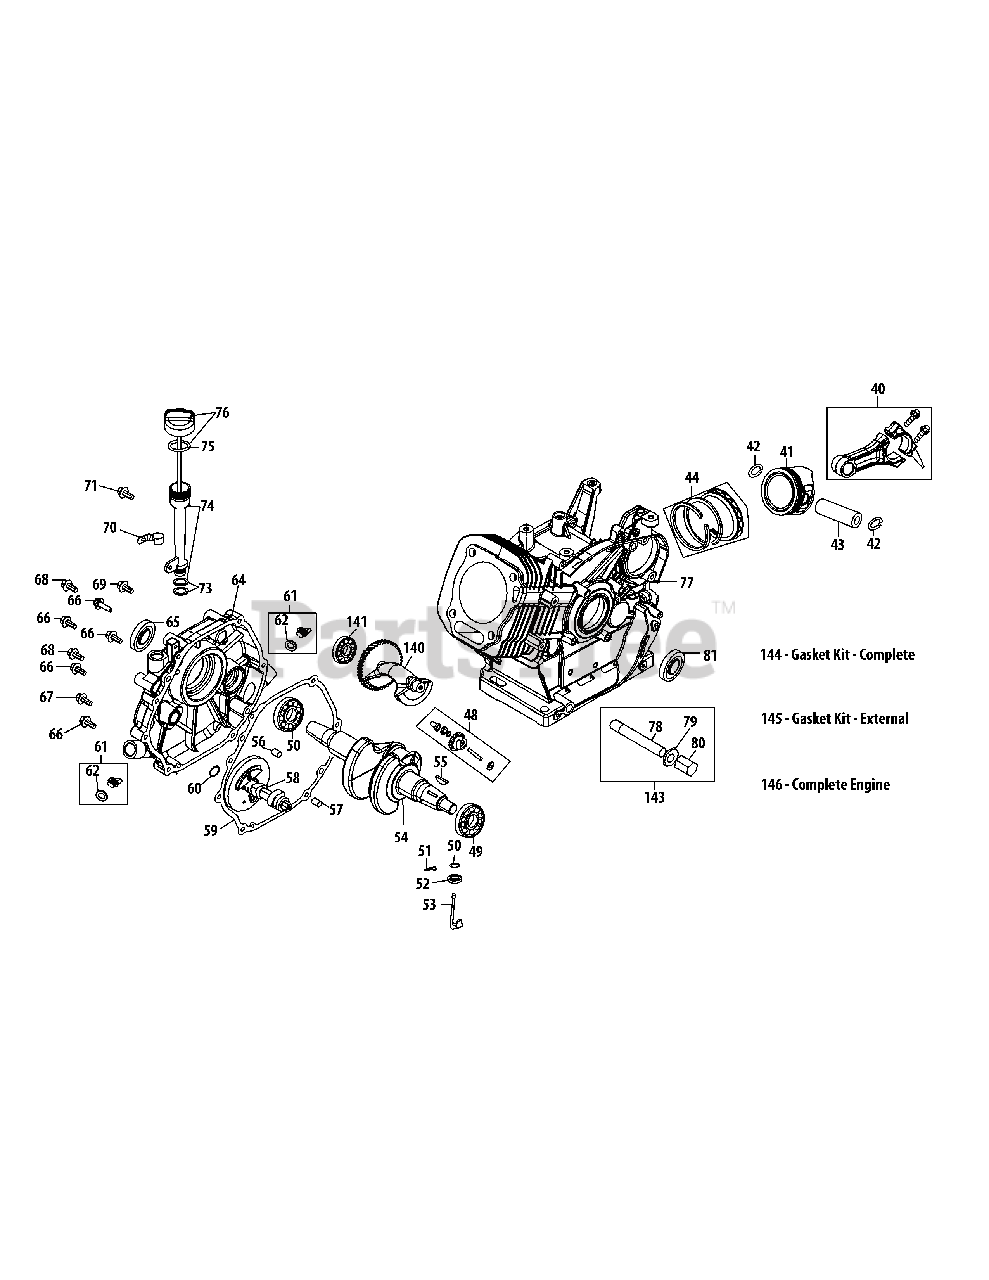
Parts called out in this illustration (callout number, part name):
40	Connecting Rod Assembly
41	Piston
42	Piston Pin Snap Ring
43	Piston Pin
44	Piston Ring Set
48	Governor Gear/Shaft Assembly
49	Radial Ball Bearing
50	Flat Washer
51	Governor Shaft Clip
52	Governor Seal
53	Governor Arm Shaft
54	Crankshaft Kit
55	Woodruff Key
56	Dowel Pin 9 X 12
57	Dowel Pin 7 X 14
58	Camshaft Assembly
59	Crankcase Cover Gasket
60	Washer
61	Oil Fill Plug Assembly
62	O-Ring
64	Crankcase Cover
64	Crankcase Cover Kit
65	Oil Seal
66	Bolt M8×38
67	Bolt M8×45
68	Bolt M8×35
69	Bolt M6×16
70	Oil Tube Support Bracket
71	Bolt M6×8
73	Oil Fill Tube O-Ring
74	Oil Fill Tube Assembly
75	Dipstick O-Ring
76	Dipstick Assembly
77	Crankcase Kit
77	Short Block Assembly
78	Oil Drain Pipe
79	Drain Pipe Washer 10X16X1.5
80	Oil Drain Plug Bolt
81	Oil Seal
140	Balance Gear Assembly
141	Bearing
143	Oil Drain Asm
144	Gasket Kit - Complete
145	Gasket Kit - External
146	Complete Engine
